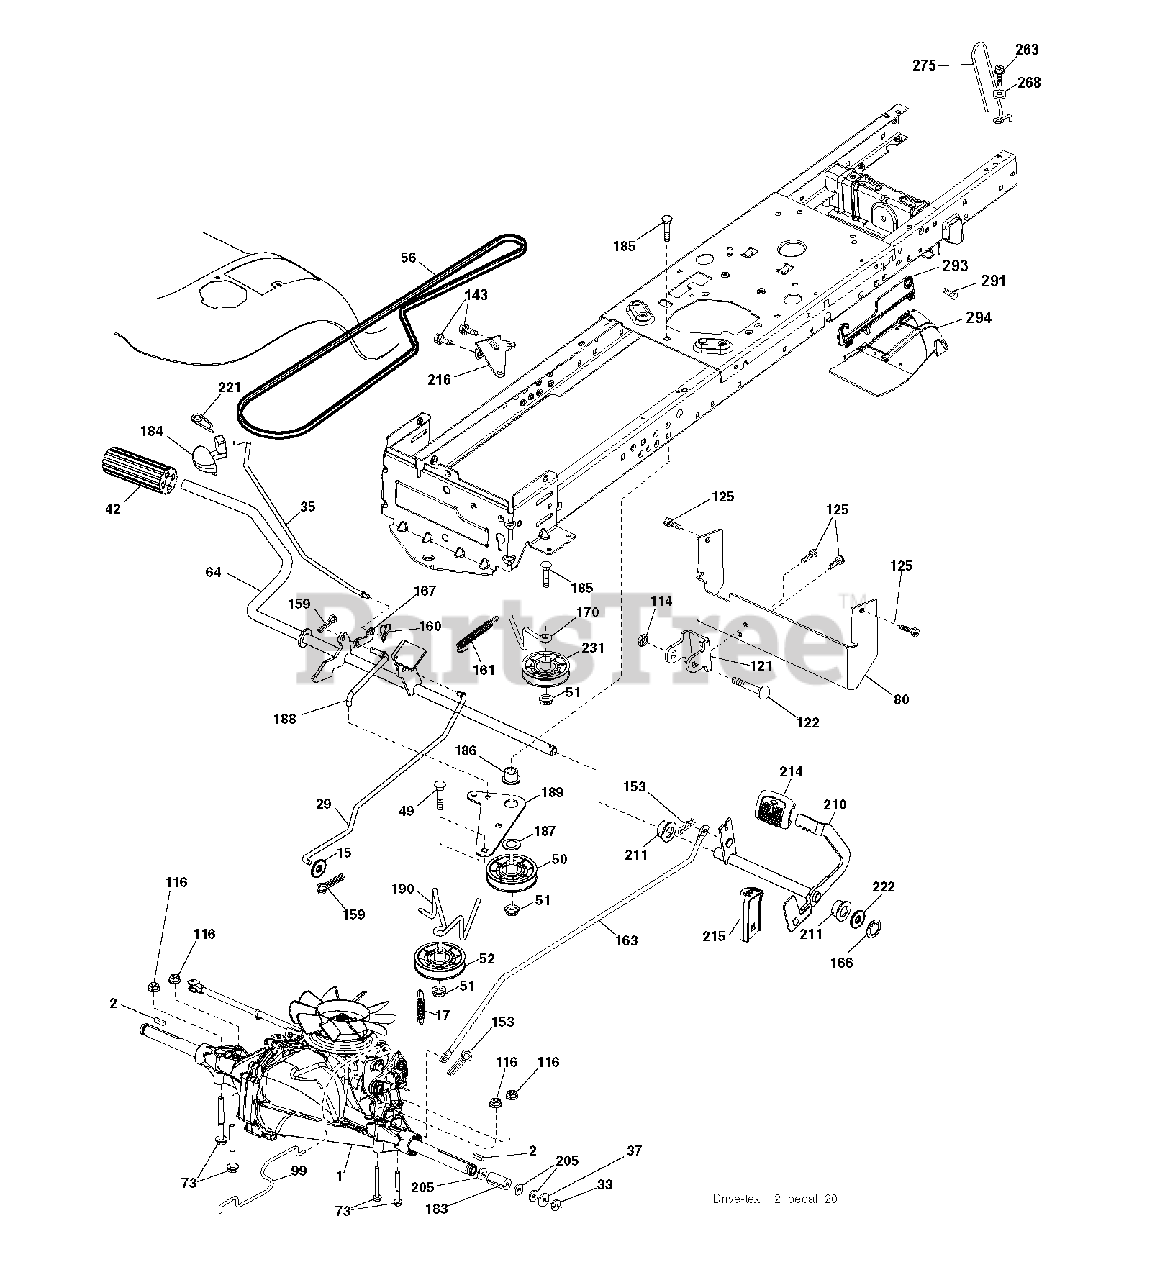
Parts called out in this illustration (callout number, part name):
2	SQUARE KEY
17	SPRING.BRAKE.HG3000/3500
29	ROD BRAKE
33	E-RING LT
35	ROD, BRAKE, PARK
42	PEDAL COVER T
49	BOLT
50	IDLER.FLAT.910.OFFSET
51	NUT LOCK FLG 3/8-16 UNC
52	IDLER.V-GROOVE.910.OFFSET
64	SHAFT.ASM.PEDAL.BRK.CNTR
73	BOLT HEX 5/16-18 GR 5
80	STRAP.TORQUE.FS.T2
99	ROD.ASM.BYPASS.SPRING.T2.FS
114	NUT.71038.31-18.HEX.NYLOCK
116	NUT LOCK HEX FLANGE 5/16-18
121	BRACKET STRAP TORQUE
122	BOLT.5/16-18X2.5
125	SCREW
143	SCREW LT
153	RETAINER M
159	COTTER PIN
160	RETAINER CLIP
161	SPRING, RETURN LT
163	ROD.CONTROL.PCH.T2.TEX
166	NUT.PUSH.625.2006
167	LATCH.BRAKE.SPRING
170	KEEPER.CENTER SPAN.1.688
183	SPACER, AXLE PVST
184	HANDLE PARKING BRAKE
186	SPACER.RETAINER
187	WASHER 12/32X2X10GA
188	LINK.CLUTCH.GROUND.DRIVE
189	BELLCRANK.GROUND.DRIVE.TEX.
190	KEEPER.BELLCRANK.DRIVE
210	ROCKER.ASM.PEDAL.CONTR
211	BEARING.NYLON
214	PAD PEDAL FORWARD
216	BRACKET.PULLEY.IDLER.W/TEX
221	RETAINER.SPRING.CLIP.H
222	WASHER 21/32 X 1-1/4 X 10 GA.
231	IDLER.V-GROOVE.1.688.OFFSET
263	SCREW, 3/8-16X3/4
268	WASHER
291	SHOULDER BOLT 5/16-18TT
